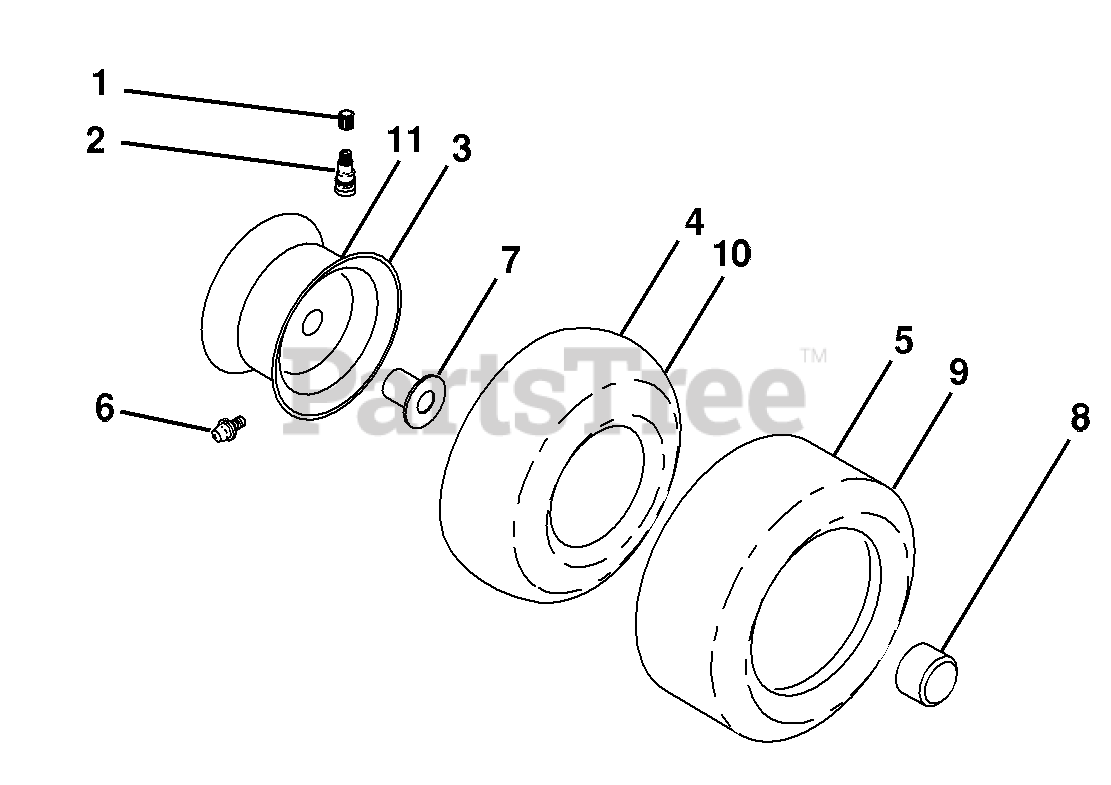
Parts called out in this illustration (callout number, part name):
1	Cap Valve Tire
2	Stem Valve
3	Rim Front Service
4	Tube Front
5	Tire Front 15 x 6.0-6 Service
6	Fitting Grease
7	Bearing Flange
8	Cap Axle Blk 1 50 x 1 00
9	Tire R T 20 x 10-8 Service
10	Tube Rear
11	Rim Asm 8" rear Service
